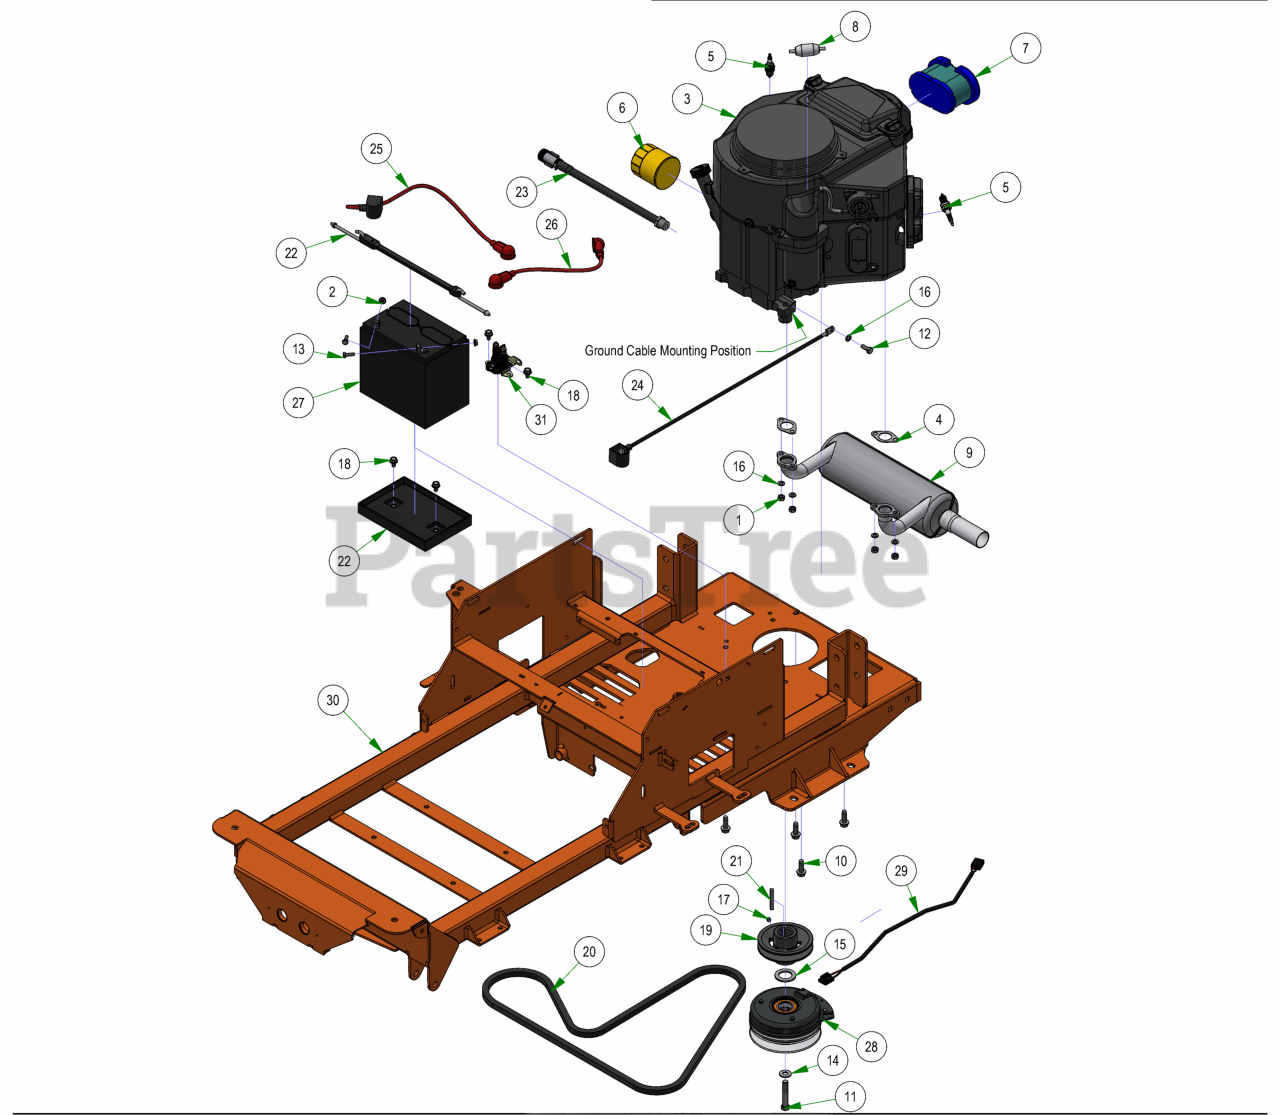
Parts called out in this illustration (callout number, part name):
1	M8-1.25 DIN 934 HEX NUT (CL.8) ZINC
2	1/4-20 HEX SERRATED FLANGE NUT HARD/ZINC
3	FS730V Engine
4	Exhaust Gasket
5	Spark Plug - Kawasaki
6	22-26 Kaw Oil Filter FR Engine
7	Kawasaki Air Filter
8	Universal Inline Fuel Filter
9	Kawasaki Muffler 1251
10	3/8-16 X 1-1/8 HEX WASHER UNSLOT SERRATED (TRI-LOB) TRS ZINC YELLOW
11	7/16-20 X 2.5" HEX Bolt GR.8 W/Patch
12	M8-1.25 X 20MM DIN 933 HEX TAP BOLT (CL 8.8) ZINC
13	1/4-20 X 3/4 HEX CAP SCREW (GR.5) ZINC
14	3/8 FLAT WASHER USS (1" OD) ZINC
15	1.140 ID X 1.750 OD X .132 THICK FLAT WASHER PLAIN
16	5/16 SPLIT LOCKWASHER ZINC
17	5/16-24 X 1/4 SOCKET SET SCREW (CUP PT) PLAIN
18	5/16-18 X 1/2 HWH unslot (F) tcs zinc
19	4 3/4 Motor Pulley
20	75.8" Pump Belt
21	1/4 X 2 SQ MACHINERY KEY 1018 STL PLAIN
22	2023 Battery Hold Down Assembly
23	Kawasaki Oil Drain
24	24 inch Black Cable – MZ/ZT
25	24" Red Battery Cable
26	12" Red Battery Cable
27	SP-35 Battery
28	120 Ft Lb. Clutch - 1 1/8" Shaft
29	Clutch Pigtail
30	2025 Maverick Frame
